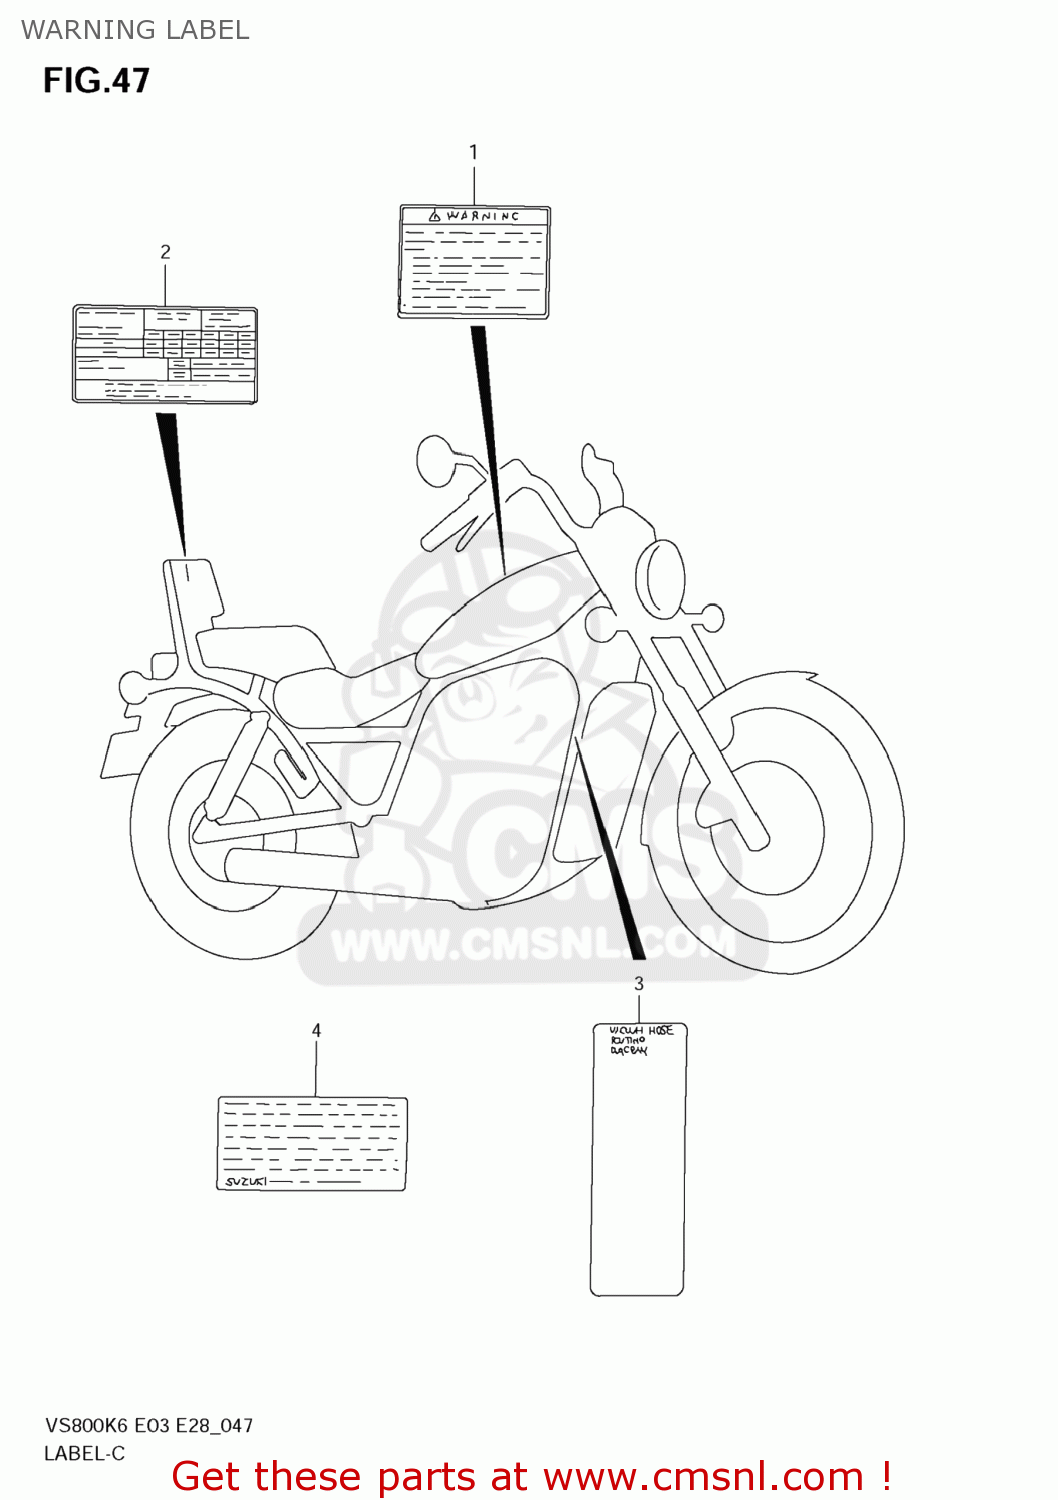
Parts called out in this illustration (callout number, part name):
1	LABEL,GENERAL WARNING
2	LABEL,TIRE INFORMATION
3	LABEL,VACUUM HOSE ROUTING
4	LABEL,MANUAL NOTICE
5	MANUAL,OWNER'S
